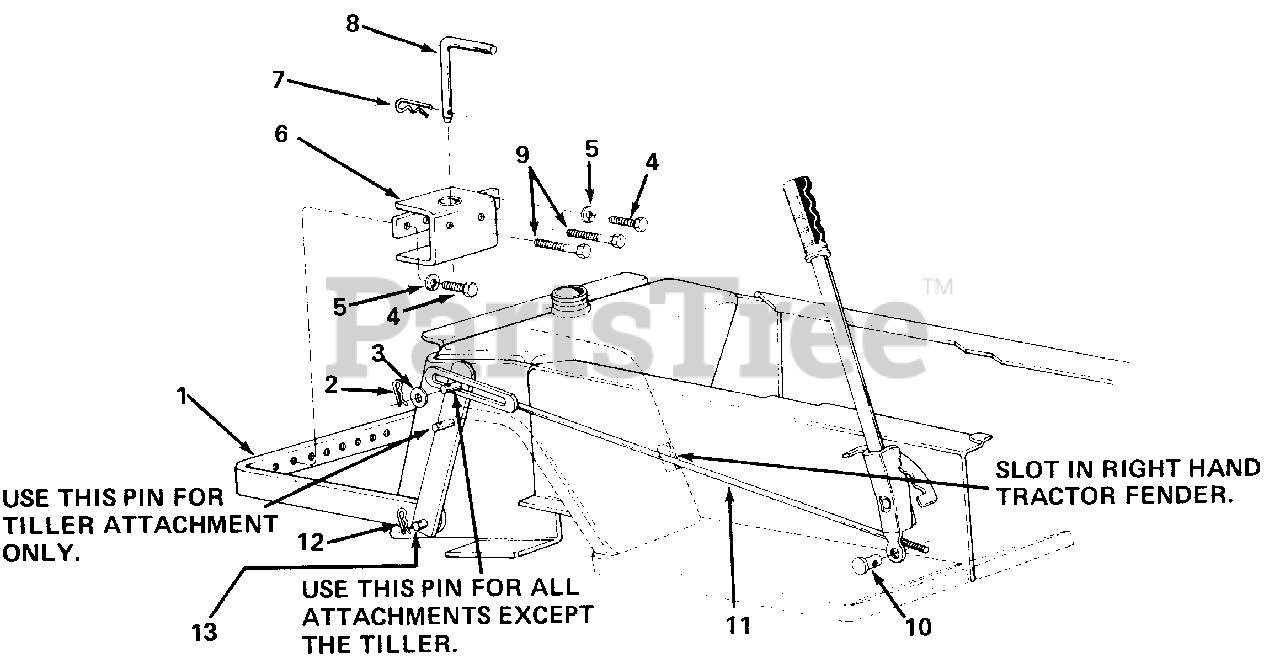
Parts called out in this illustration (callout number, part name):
3	Fl.-Wash. 1/2" I.D.
4	Hex Scr. 1/2-13 x 1.00" Lg.*
5	L.-Wash. 1/2" Scr.*
8	Hitch Pin
9	Hex Scr. 1/2-13 x 3.00 " Lg. *
10	Adjustment Ferrule
13	Hitch Rod
